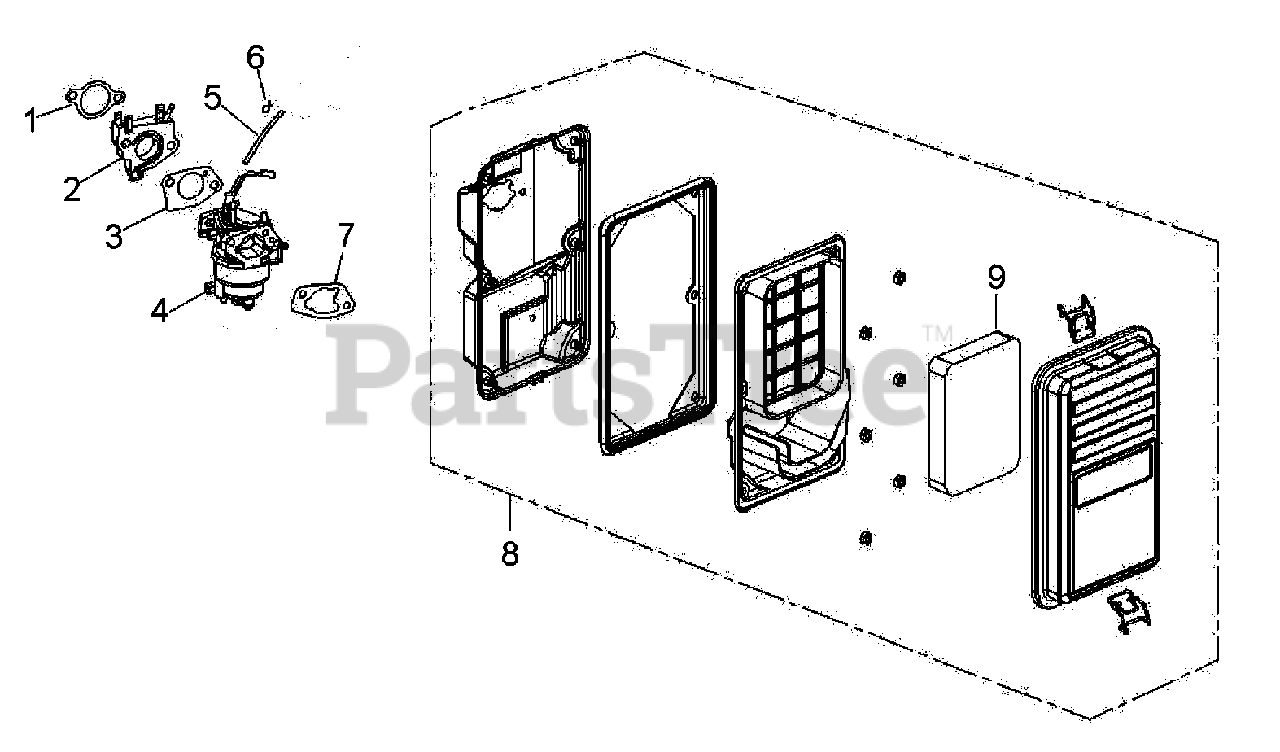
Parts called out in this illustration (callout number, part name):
1	GASKET, CARBURETOR
2	SPACER, CARBURETOR
3	GASKET, CARBURETOR
4	CARBURETOR ASSY.
5	TUBE, FUEL
7	GASKET, CARBURETOR
8	AIR CLEANER ASSY.
9	ELEMENT, AIR CLEANER
